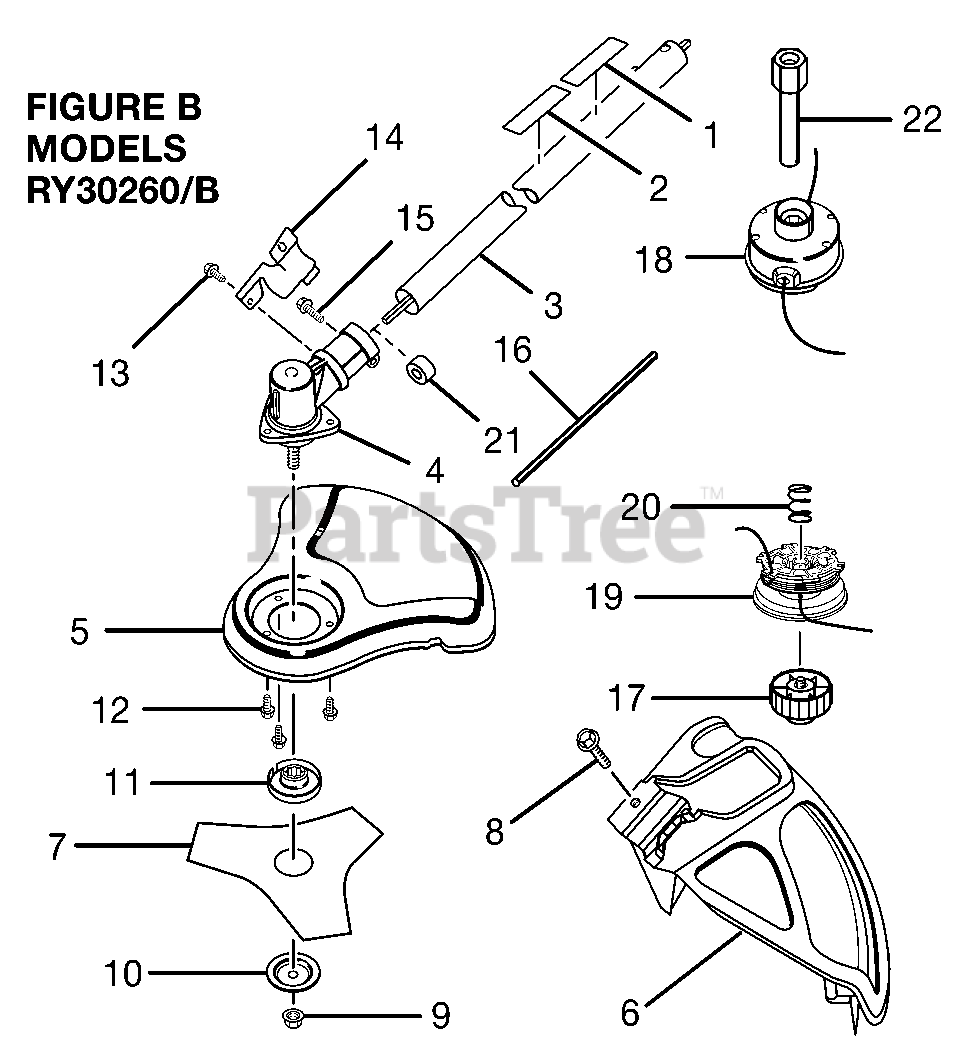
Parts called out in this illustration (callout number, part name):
1	Expand-it Label
2	Warning Decal
3	Brushcutter Assy.
4	Gear Case Assembly
5	8 in. Blade Guard
6	Grass Deflector Assy.
7	Tri-Arc® Blade
8	Screw (1/4-20 x 0.70-0.75 in.)
9	Lock Nut
10	Cupped Washer
11	Flanged Washer
12	Screw (10-24 x 1/2 in.)
13	Screw (10-24 x 5/8 in.)
14	Clamp
15	Screw (1/4-20 x 1-1/4 in.)
16	Holding Pin
17	Spool Retainer (Red)
18	Complete String Head (.095 in.)
19	Spool and String (.095 in.)
20	Compression Spring
22	Shaft Adapter
